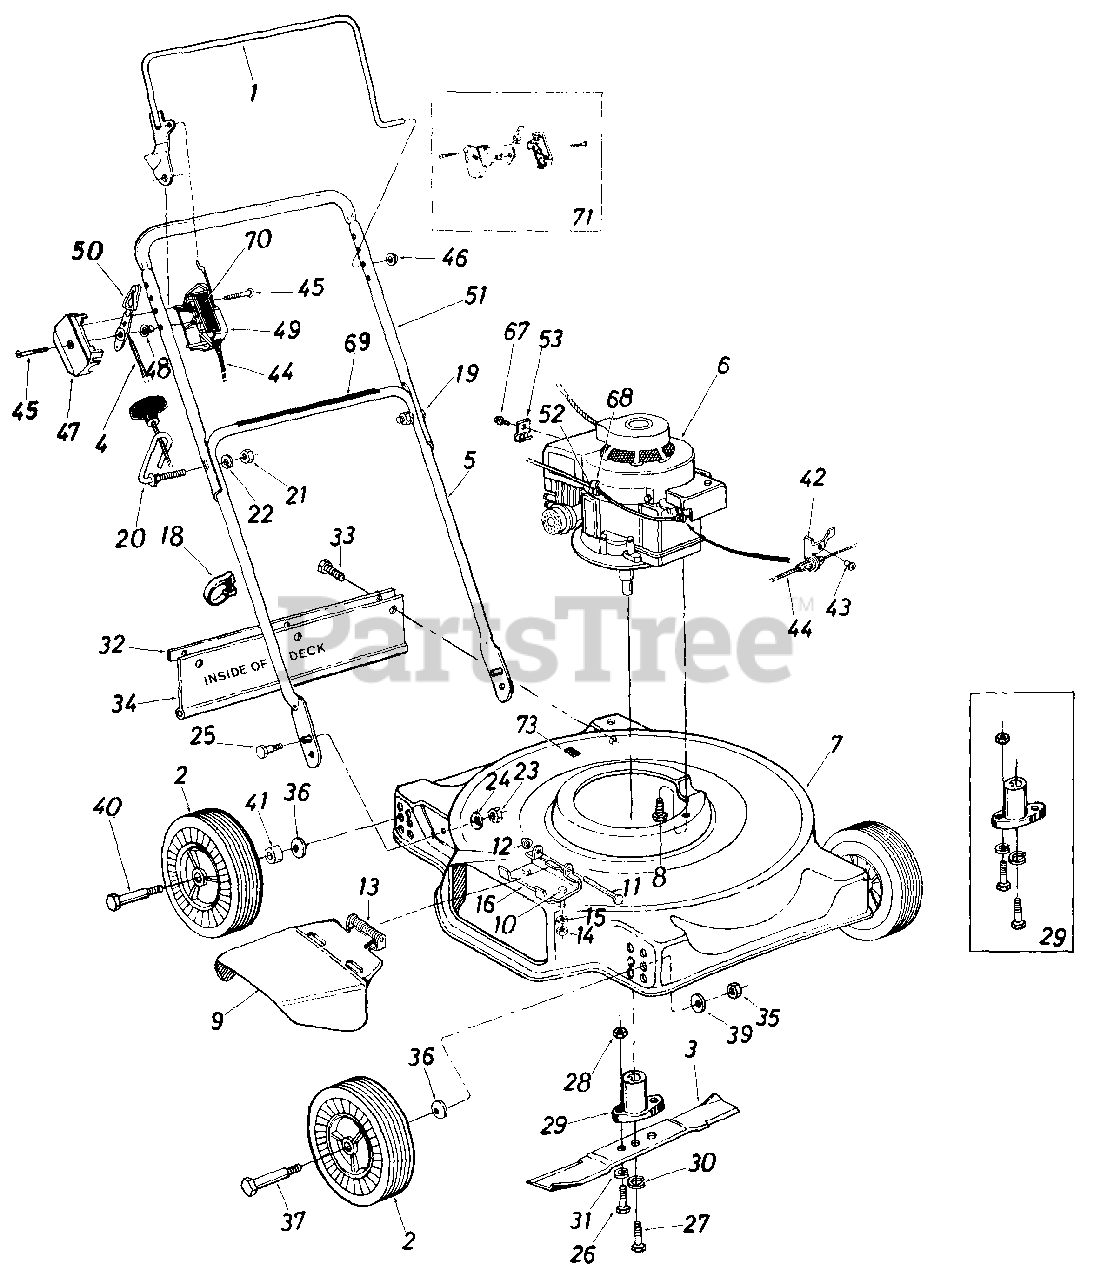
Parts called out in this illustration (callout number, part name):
1	Control Handle Ass'y. - R.H.
2	Wheel Ass'y. Comp.
3	20" Blade
4	Throttle Control Wire - 39"
5	Lower Handle
6	Engine
7	20" Deck Ass'y.
8	Hex Wash. Hd. TT-Tap Scr. 3/8-16 x 1.00" Lg.
9	Chute Deflector Ass'y.
10	Hex Bolt 1/4-20 x .50" Lg.
11	Hinge Pin 1/4" Dia. x 3.88 Lg.
12	Push Cap .25" Rod
13	Torsion Spring
14	Hex Nut 1/4-20 Thd.
15	L-Wash. 1/4" I.D.
16	Deflector Hinge Plate
18	Cable Tie
19	Curved Carriage Bolt 5/16-18 x 1.38" Lg.
20	Rope Guide Bolt
21	Hex Nut 5/16-18 Thd.
22	L-Wash. 5/16" I.D.
23	Hex Ins. L-Nut 5/16-18 Thd.
24	Bell-Wash. .345" I.D. x .88" O.D.
25	Shld. Bolt .437" Dia. x .268
26	Hex Bolt 5/16-24 x 1.00" Lg. (Grade 5) Special
27	Hex Bolt 3/8-24 x 2.25" Lg. (Grade 5)
28	Hex Nut 5/16-24 Thd.
29	Blade Adapter Kit
30	L-Wash. 3/8" I.D. - H.D.
31	L-Wash. 5/16" I.D.
32	Retainer Strip
33	Hex Wash. Hd. AB-Tap Scr. 1/4" x .62" Lg.
34	Rear Flap Ass'y.
35	Hex Nut 3/8-16 Thd.
36	Bell-Wash. .400" I.D. x .88"
37	Front Axle Bolt
39	Bell-Wash. .39" I.D. x 1.13" O.D.
40	Rear Axle Bolt
41	Spacer .511 I.D. x .70" O.D.
42	Cable Bracket
43	Pop Rivet .156" Dia. x .379
44	Control Cable - 43" (Yellow)
45	Truss Mach. Scr. #12 x 1.50"
46	Cap Speed Nut 5/16" Rod
47	Control Panel Half
48	Control Disc Pin
49	Clutch Panel Half
50	Throttle Control Lever
51	Upper Handle
52	Hex "B" Tap Scr. #10 x .38"
53	Casing Clamp
67	Hex Wash. Hd. AB-Tap Scr. #8 x .38" Lg.
68	Cable Clip
69	Instruction Label - Handle
70	Control Label - Throttle
71	Kit - Control Housing Comp.
73	Plastic Plug
